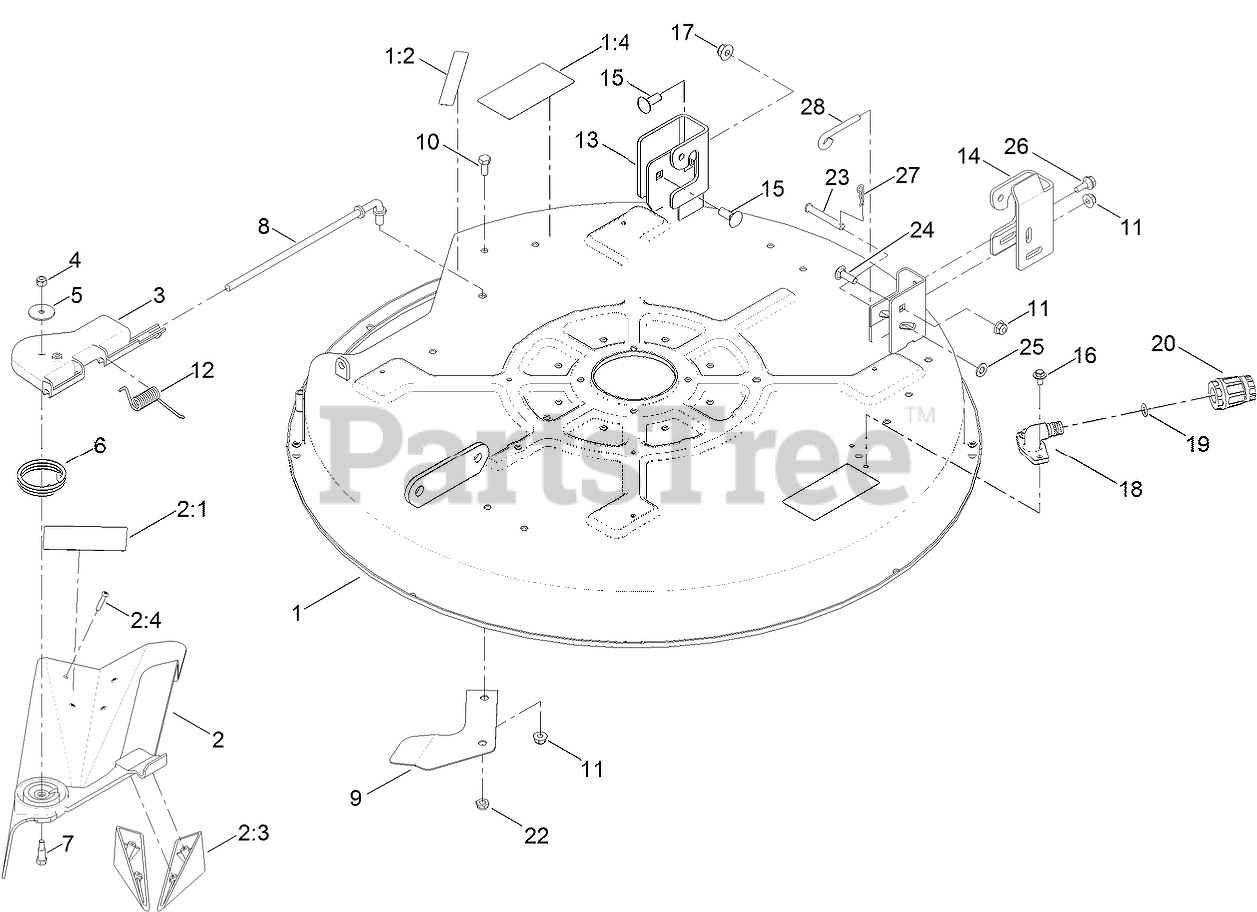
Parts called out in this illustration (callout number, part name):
1	32 INCH DECK AND DECAL ASM
1:2	DECAL-DANGER
1:4	DECAL-DANGER, DECK
2	32 INCH DEFLECTOR ASM
2:1	DECAL-DANGER
2:3	KICKER
2:4	SCREW-PPH
3	PIVOT-HINGE, DEFLECTOR
4	NUT-LOCK, NI
5	WASHER-FLAT
6	SPRING-TORSION
7	BOLT-SHOULDER
8	ROD-PIVOT
9	RAMP-DEFLECTOR
10	SCREW-HH
11	NUT-HF, NI
12	SPRING-TORSION
13	BRACKET-HANGER, RH
14	BRACKET-HANGER, LH
15	BOLT-CARR
16	SCREW-HHFTF
17	NUT-HF, NI
18	FITTING-WASHOUT
19	O-RING
20	CONNECTOR-HOSE
22	NUT-LOCK, NI
23	PIN-CLEVIS
24	SCREW-CARR
25	WASHER-PLAIN
26	SCREW-SHOULDER, HHF
27	PIN-COTTER
28	ROD-LEVEL, DECK
